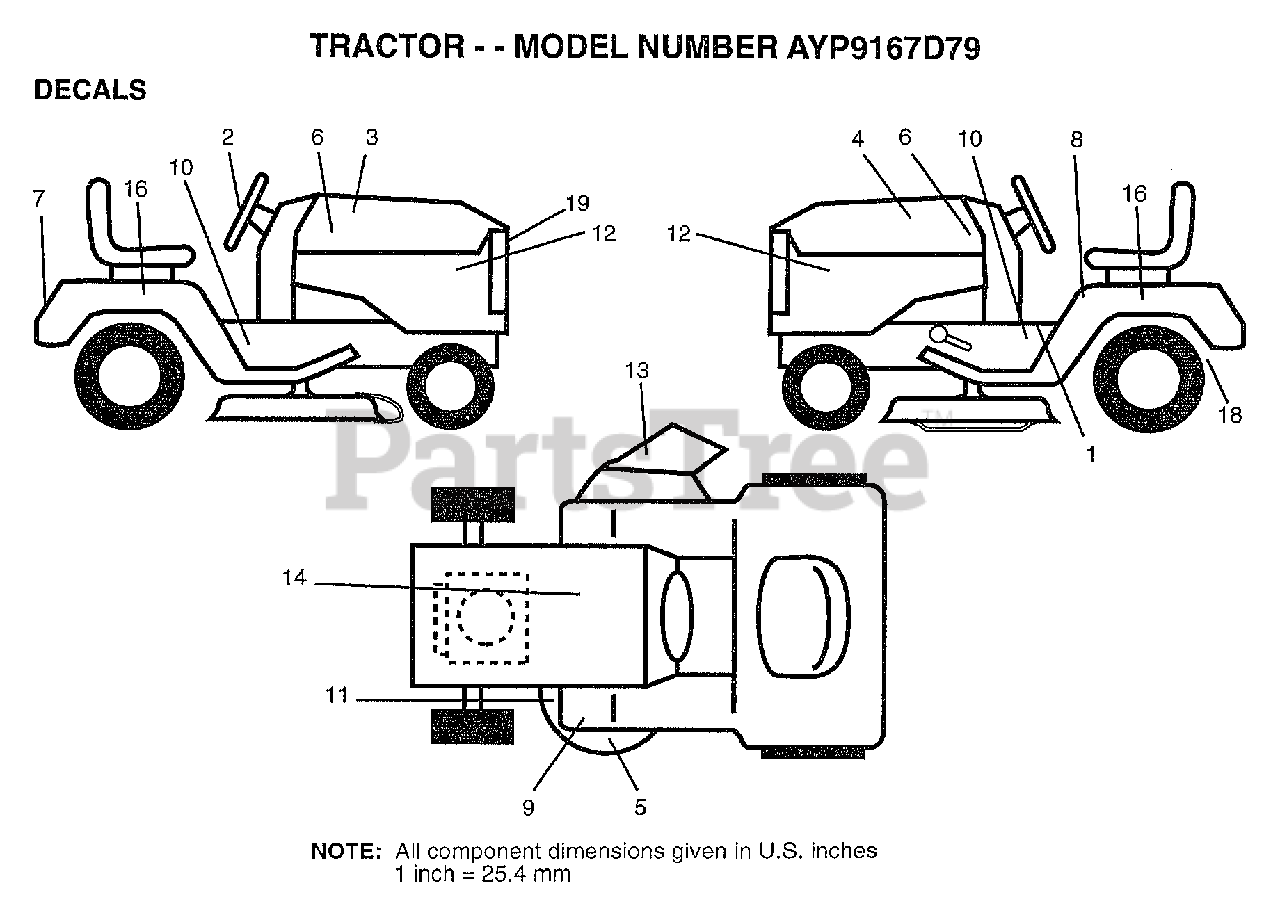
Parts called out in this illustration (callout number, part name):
1	"DECAL INST,SADDLE"
2	DECAL STEER WHL
3	DECAL HOOD RH
4	DECAL HOOD LH
5	DECAL DECK WIZ +
6	NAMEPLATE.HD.WIZA
8	"DECAL DANGER,FEND"
10	"DECAL.CHASSIS.42"""
11	"DECAL-SCHEM,BELT"
12	"DECAL PANEL,SIDE"
13	DECAL DECK MULCH
14	DECAL.BATRY.3-3908
16	DECAL.FENDER.WIZ
18	DECAL DRAWBAR LH
19	DECAL.LENS.WIZARD
